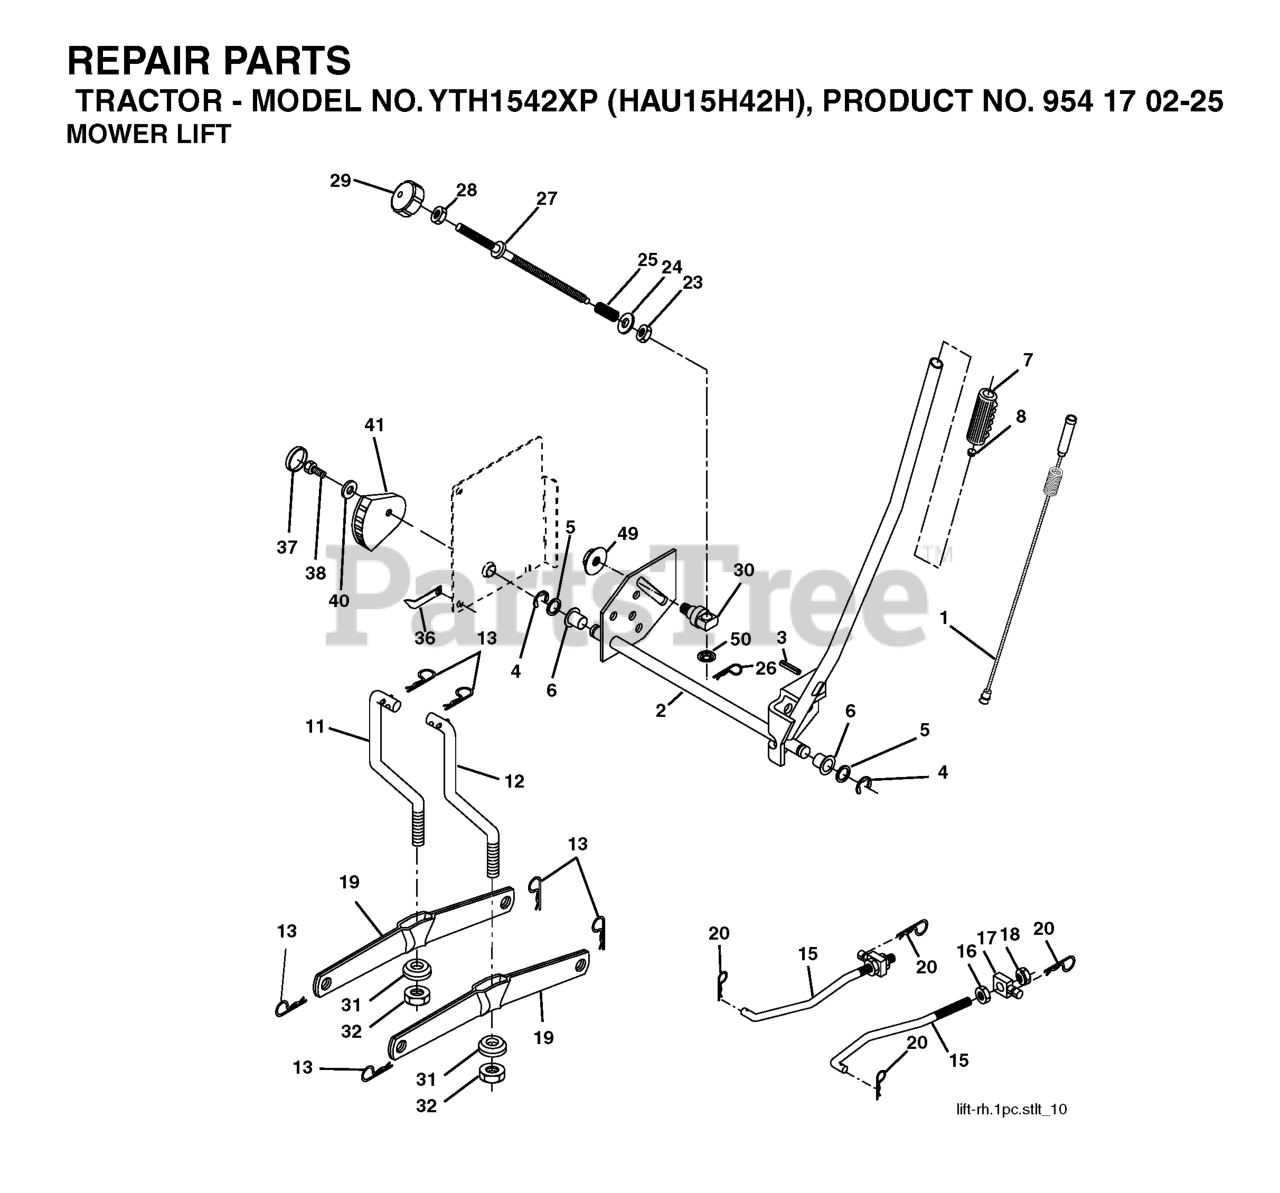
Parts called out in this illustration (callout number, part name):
1	WIRE.ASM.INNER.SP
2	SHAFT.ASM.LIFT.RH.INF
3	PIN.GROOVE.5/16
4	RETAINING RING LT
6	BEARING.NYLON
7	GRIP HANDLE
8	PLUNGER BUT KIT
11	LINK LIFT LH
12	LINK LIFT RH
13	RETAINER-SPRNG RB
15	LINK.SUSPENSION.FRONT
16	NUT.HEX.JAM.1/2-13
18	NUT.LK.W/WSH.1/2.
19	ARM.REAR.SUSPENSION
20	SPRING RETAINER
26	RETAINER CLIP
27	ROD ADJ LIFT
28	NUT
29	KNOB INF 3/8-16
31	BEARING.PIVOT.LIFT
32	NUT CROWNLOCK 3/8-24
36	POINTER, HEIGHT INDICATOR(2 2)
38	SCREW 5/16-18X1
41	IND. HEIGHT STLT
49	NUT
50	NUT PUSH M
